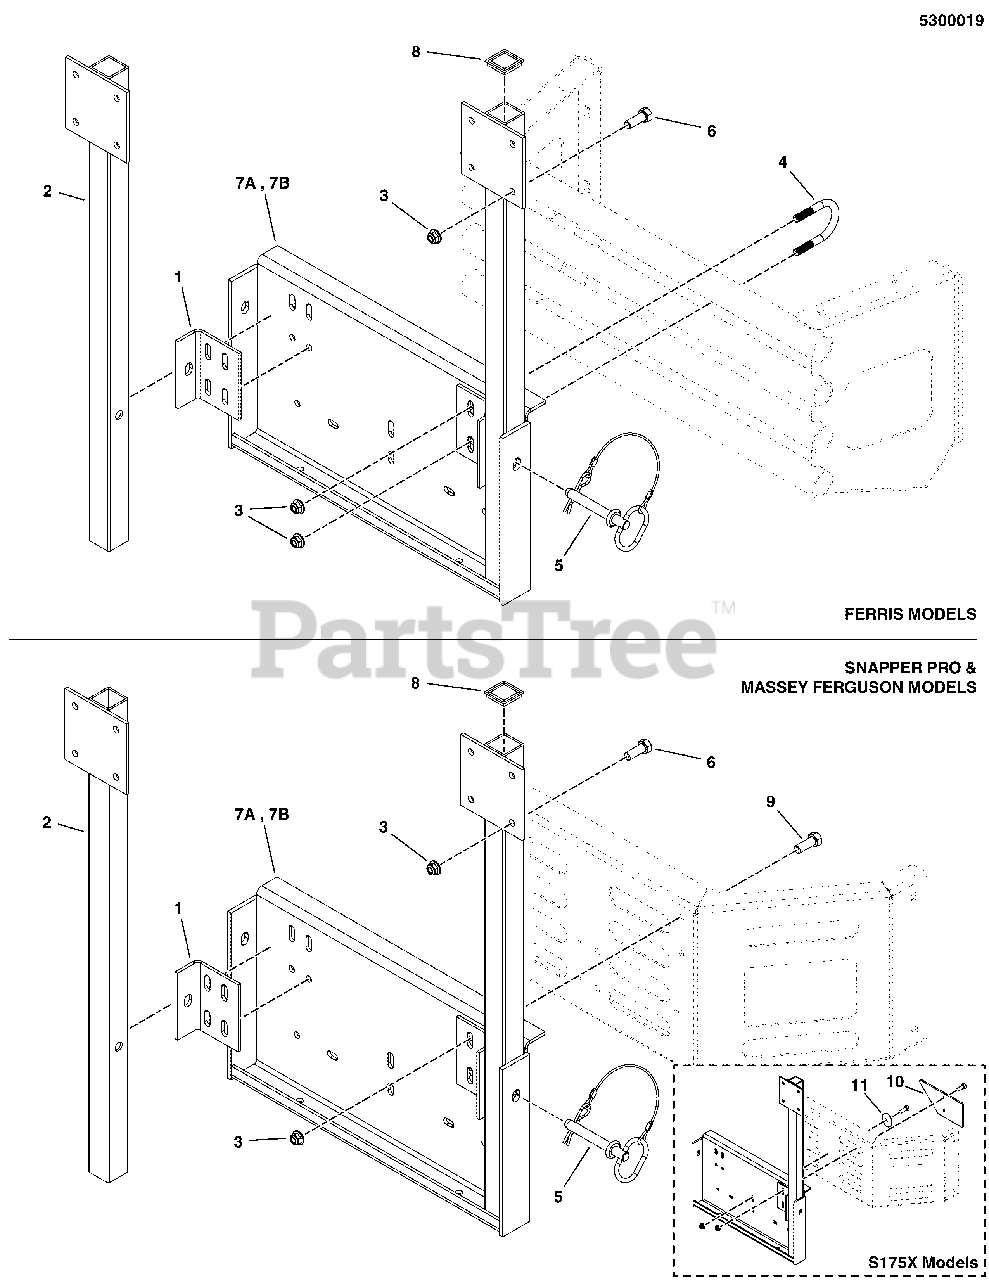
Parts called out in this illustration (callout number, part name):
1	BRACKET, BAGGER MOUNT - BLK
2	WELD, MOUNT, POST - BLK
3	NUT, 3/8 - 16 HEX NYLOCK FLANGE
4	U-BOLT, 3/8" X 1-1/4"
5	PIN, HITCH, .50 X 3.25 W/ LAY (SV)
6	BOLT, 3/8-16 X 1" GD5 CZ
7A	WELD, BAGGER MNT,500/1500/4500-BLK
7B	WELD, BAGGER MNT,1500/4500-BLK
8	CAP, PLASTIC, 1-1/2" X 1-1/2
9	BOLT, 3/8-16 X 1-1/4" GD5 CZ
10	PLATE, SUPPORT, BAGGER MOUNT - BLK
11	WASHER, .39 X 2.00 X X .14
